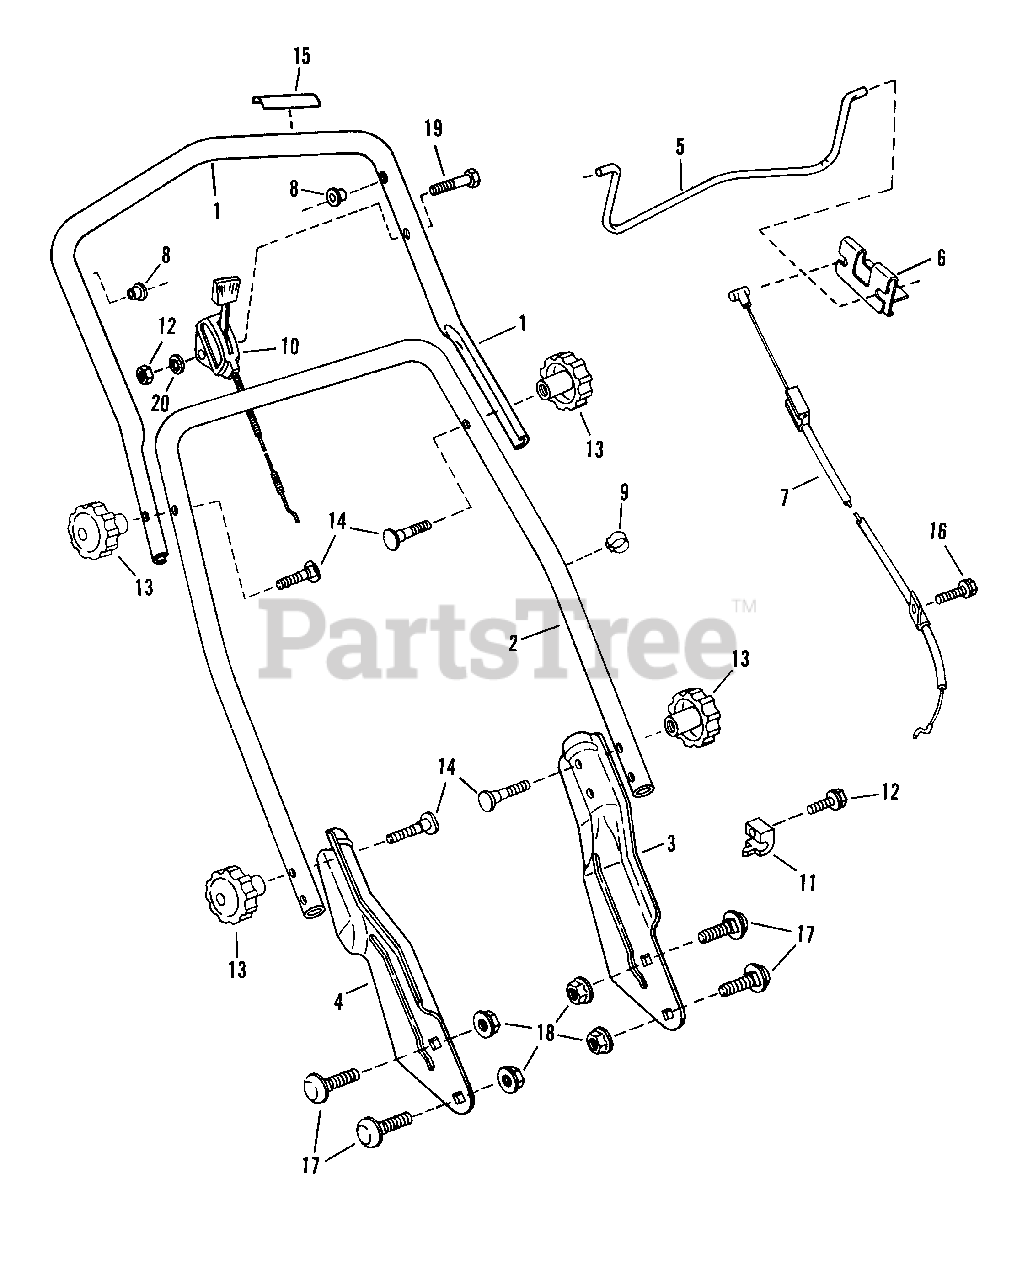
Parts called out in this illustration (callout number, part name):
1	HANDLE, Upper
2	HANDLE, Middle
3	HANDLE, Lower Left Hand
4	HANDLE, Lower Right Hand
5	CONTROL, Blade
6	CLIP, Blade Control
7	CABLE, Blade Control
8	BUSHING
9	CLIP, Cable/Wiring
10	CONTROL, Throttle
11	CLAMP, Casing
12	SCREW, #10-32 x 5/8" Self-Tapping
13	KNOB, 5/16-18
14	SCREW, 5/16-18 x 2" Curved Head
15	DECAL, Blade Control
16	SCREW, #10-32 x 3/8" Hex Head Cap,
17	BOLT, 5/16-18 x 5/8" Short Neck Carriage, Grade 5
18	NUT, 5/16-18 Hex Flange Lock, Grade 5
19	SCREW, 1/4-28 x 1-3/4" Hex Head Cap, Grade 5
20	WASHER, 1/4" Internal Tooth Lock
21	NUT, 1/4-28 Hex, Grade 5 or B
